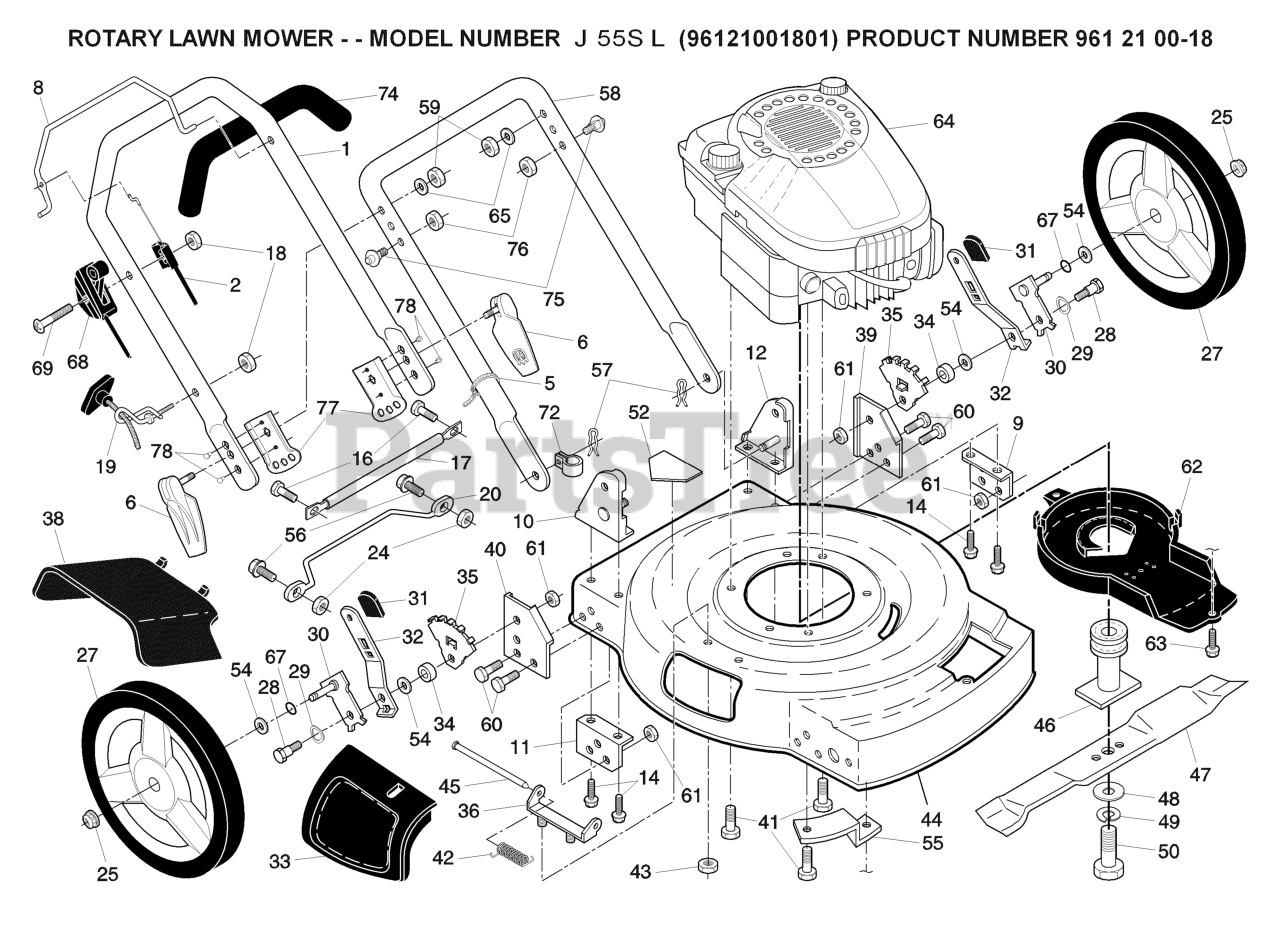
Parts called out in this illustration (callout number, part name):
1	Upper Handle
2	ENGINE ZONE CONTROL CABLE
5	TIE GUIDE
6	ASM.QUICK.RELEASE
8	BAIL.COMF.FWGD.668.ORANGE.WALK
9	GUARD.SLKSCR.BELT.
10	Handle Bracket Assembly, RH
11	Support Bracket, Handle, RH
12	Handle Bracket Assembly, LH
14	SCREW.5/16-18X3/4
17	SUPPORT ROD
18	NUT
19	RB GUIDE.ROPE.STD.BLK.ZIN WSL
25	NUT.HEX.FLANGE.3/8-16.LOCKNUT
27	WHEEL ASSY
28	BOLT
29	WASHER.CURVED.CYLINDRICAL
30	ARM.ASM.AXLE.5/9.POS.BZP
31	SELECTOR KNOB
32	SELECTOR SPRING, FRONT
33	DOOR.MULCH.22.EZ.MULCH.GREY
34	SPACER.HEIGHT.ADJUSTER
35	BRACKET.ADJ.WHEEL.5POS.ADS
36	BRACKET.ASM.HOUSING.EZ.MUL
38	DEFLECTOR.GUARD.22..EZ.MULCH
39	BRACKET.SUPPORT.LT.12.WHL.ORNG
40	BRACKET.SUPPORT.RT.12.WHL.ORNG
41	BOLT 3/8-16X1-1/8
42	TORSION SPRING
43	LOCKNUT.NYLOC.1/4-20
44	Kit, Mower Housing
45	ROD.HINGE.COMBI-C
46	ADAPTER.BLADE/PULLEY.25M
47	Blade, 22"
48	WASHER,HARDEN
49	LOCKWASHER
50	SCREW, HEX HD 3/8-24 X 1-3/8
52	DECAL.INTERNATIONL.CUTFINGER
54	WASHER.FLAT.1/2
55	BRACKET
56	REPL BY 817 02 10-08
57	HAIRPIN COTTER
58	HANDLE LOWER EZ 2POS GRAY
59	Locknut, Hex 1/4-20
61	LOCKNUT
62	DEBRIS SHIELD
63	SCREW.HEX.WSH
65	WASHER.20X8.5
67	O-RING..070X.487.NEOPRENE
68	Control Throttle
72	CLIP.CABLE.BLK
74	GRIP.HANDLE.FOAM
75	STUD.QUICK.ADJUST
76	NUT.LOCK.5/16-18
77	BRACKET.ADJ.3POS.GREY
